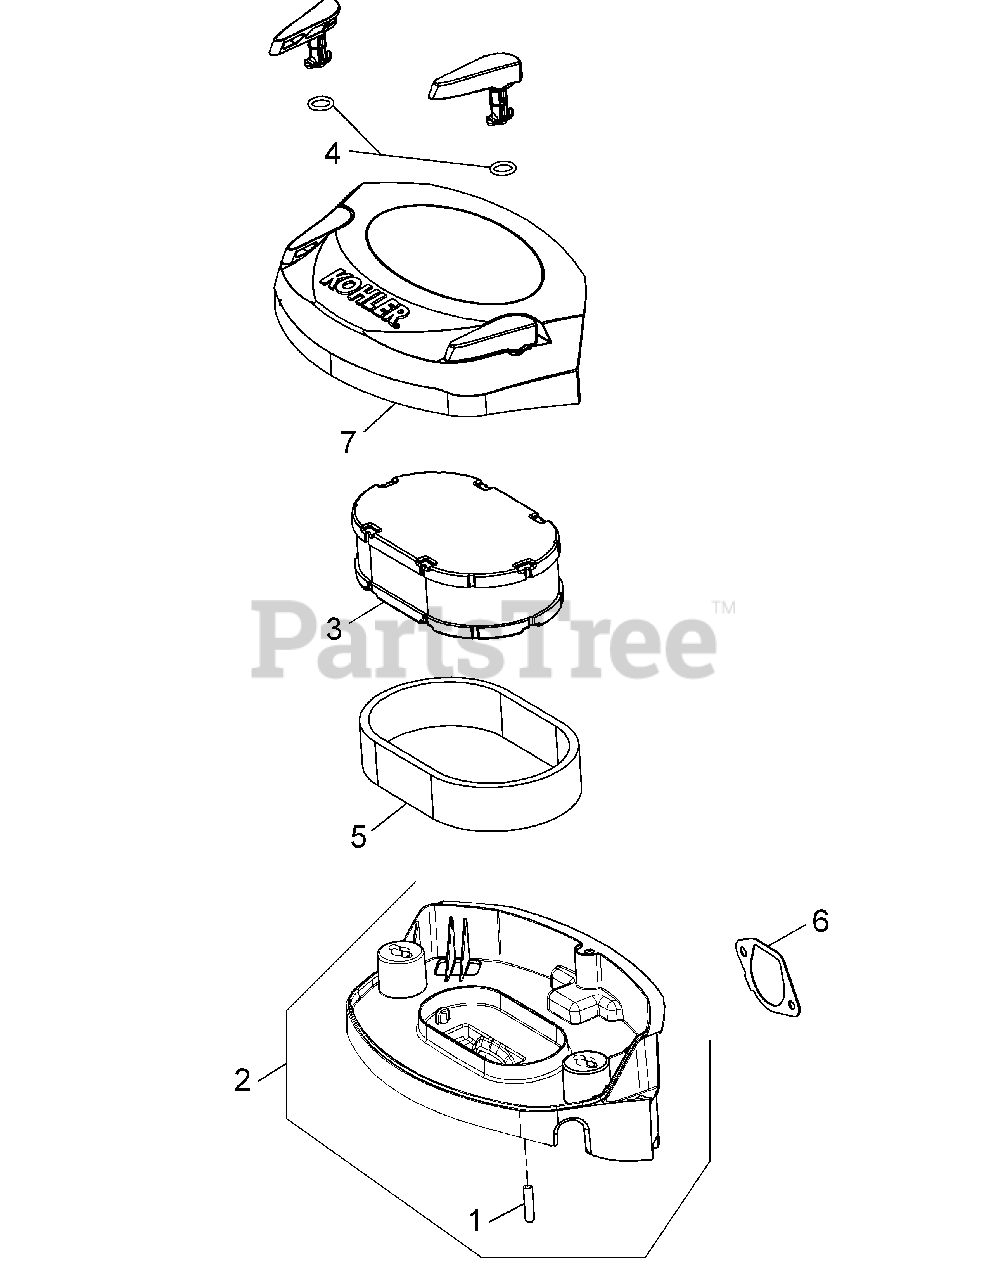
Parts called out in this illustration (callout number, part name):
2	Air Cleaner Base Assembly
3	Air Filter Element
5	Pre-Cleaner Element
6	Air Cleaner Base Gasket
7	Air Cleaner Cover Assembly
